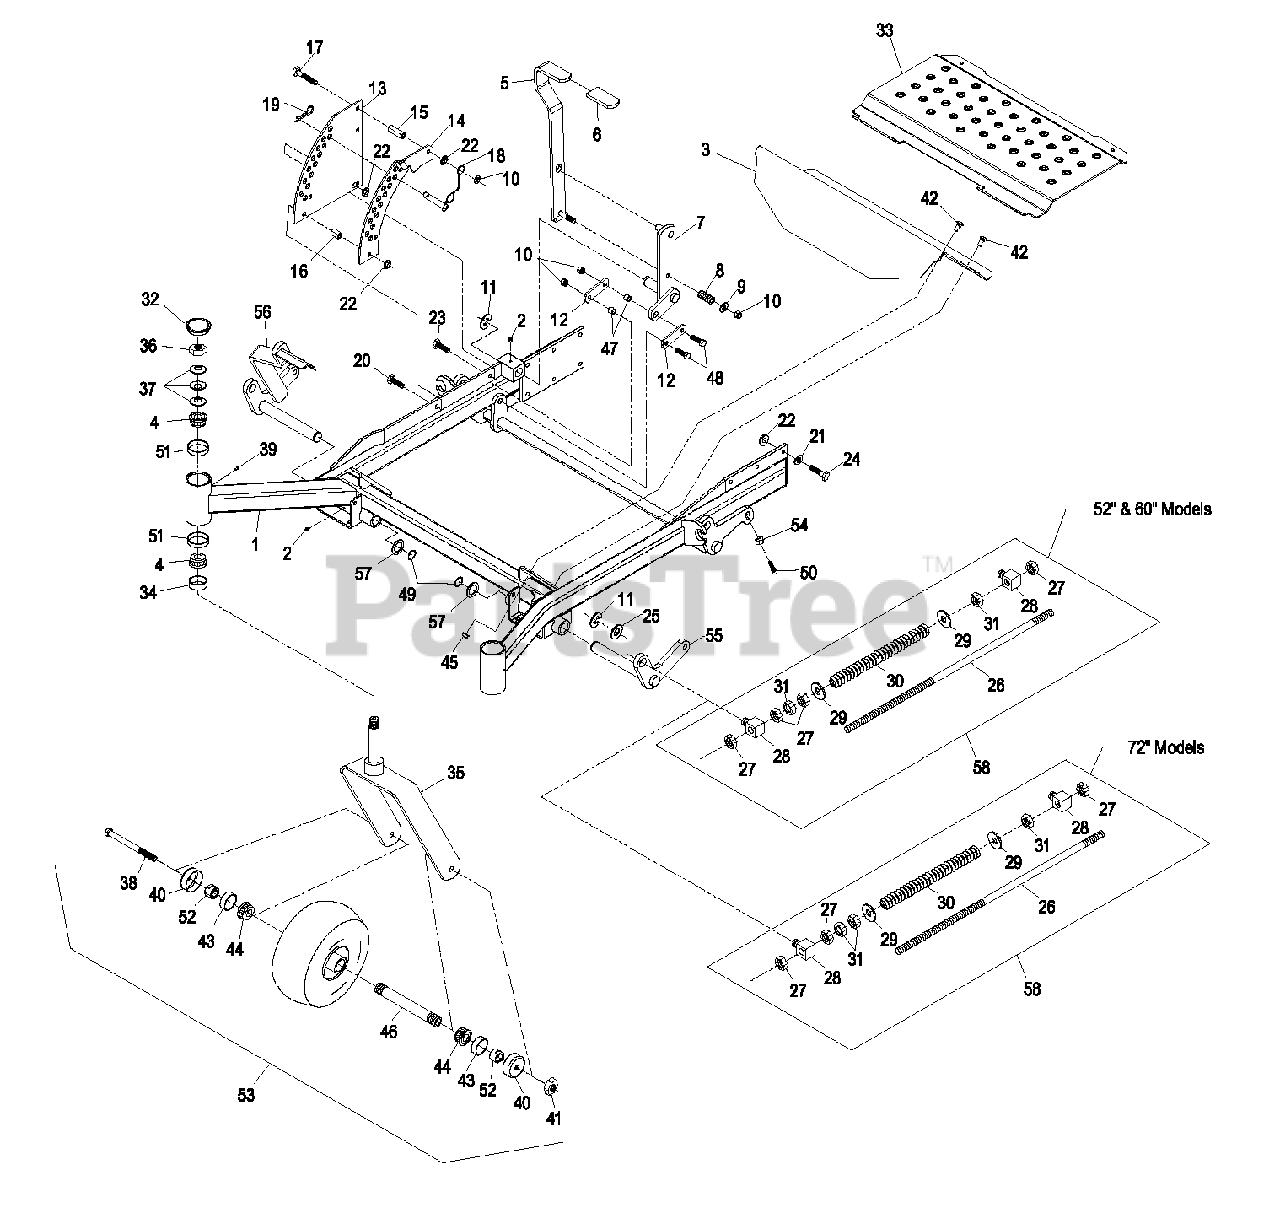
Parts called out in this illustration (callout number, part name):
1	KIT,FRONT FRAME LZ 52
1	KIT,FRONT FRAME LZ 60
1	KIT,FRONT FRAME LZ 72
2	FITTING-GREASE
3	ASM, FLOORPAN FRONT W/DEC
4	Cone-Bearing Tapered Roller
5	LIFT LEVER/GRIP ASM
6	GRIP-LEVER, LIFT
7	ARM-LIFT, DECK
8	SPRING-COMPRESSION
9	WASHER-FLAT
10	NUT-LOCK, NI
11	RING-RETAINING, EXT
12	ARM-LIFT, DECK
13	PLATE-LIFT, DECK
14	PLATE-LIFT,DECK W/DECAL L
15	BUSHING-LEVER, LIFT
16	BUSHING-LEVER, LIFT
17	SCREW-HH
18	PIN-HITCH (W/LANYARD)
19	PIN-COTTER
20	SCREW-HH
21	WASHER-BELLEVILLE
22	NUT-HHF, WHIZ
23	SCREW-HH
24	SCREW-HH
25	WASHER-FLAT
26	ROD-LIFT, DECK
27	NUT-HEX
28	SWIVEL-DECK MOUNT, REAR
29	WASHER-FLAT
30	SPRING-SUPPORT, DECK
31	NUT-JAM
32	CAP-GREASE
33	ASM, FLOORPAN LIFTOUT W/D
34	SEAL-GREASE
36	NUT-LOCK, NI
37	WASHER-BELLVILLE
38	SCREW-HH
40	GUARD-SEAL
41	NUT-LOCK, NI
42	BOLT-CARR
43	SEAL-CASTER
44	BEARING-CONE, TAPERED ROLLER
47	BUSHING
48	SCREW-HH
49	RING-RETAINING
50	SCREW-HSH
51	CUP-BEARING
52	SPACER-NUT
53	ASM, WHEEL AND TIRE W/ AX
54	Nut, 5/16-18
55	WLD, FRONT LIFT SHAFT - L
56	WLD, FRONT LIFT W/ LEVER
57	WASHER-SPACER
58	FRONT FRAME SPRING ASM
